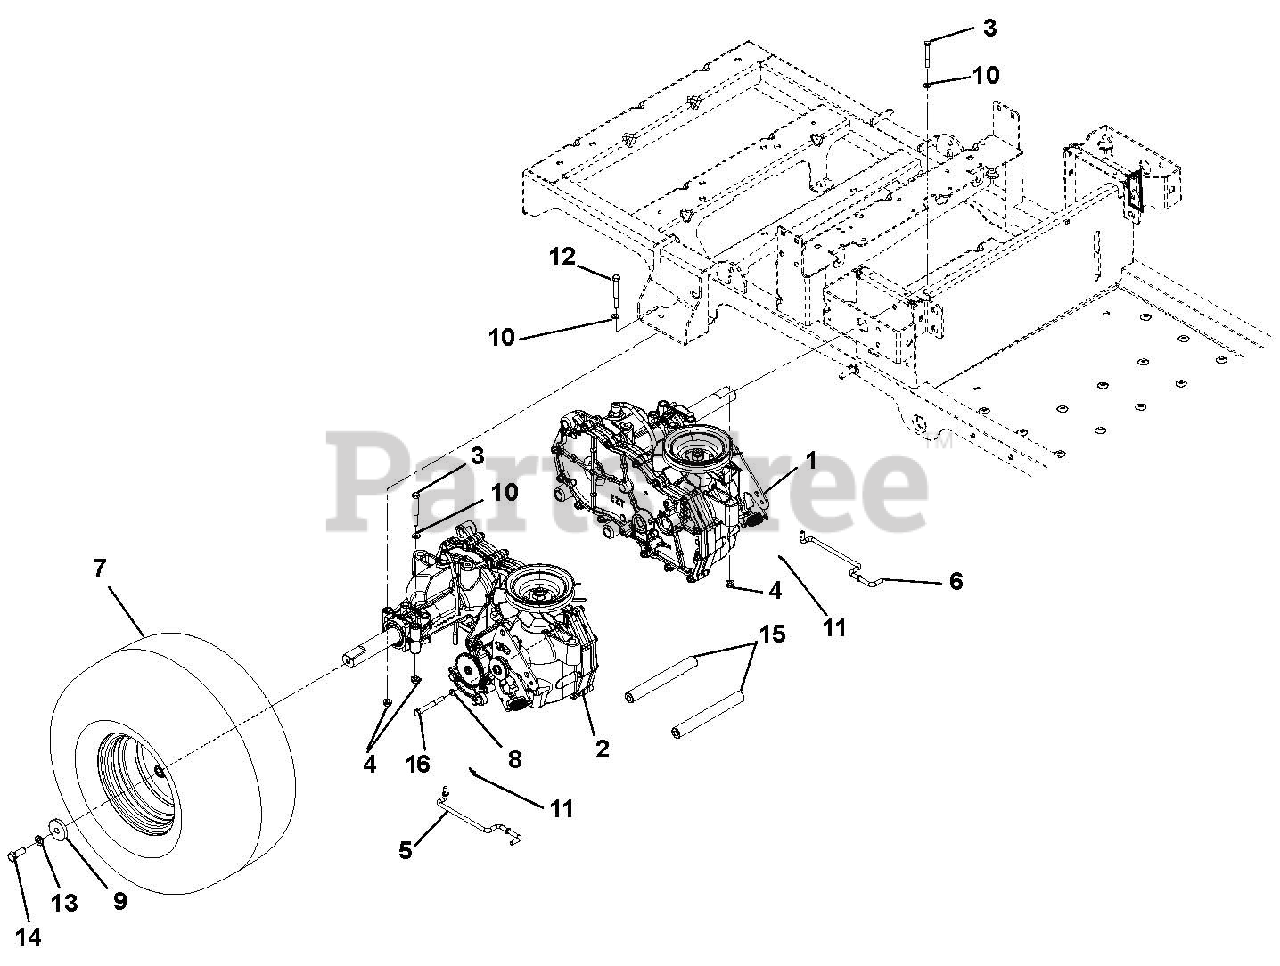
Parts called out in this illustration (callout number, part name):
1	Transaxle, Left Hand EZT D-Shaft
1	Transaxle, Left Hand EZT D-Shaft Long
2	Transaxle, Right Hand EZT D-Shaft
2	Transaxle, Right Hand EZT D-Shaft Long
3	Bolt, Hex .31-18 x 2.25
4	Nut 5/16-18 Flange Nyloc
5	Dump Valve, Right Hand
6	Dump Valve, Left Hand
7	Tire Assembly 18 x 6.5-8 2 Ply DSHAFT
7	Tire/Wheel Assembly, 18 x 8.5-8 Center
7	Tire/Wheel Assembly, 18 x 9.50-8 Offset
8	Washer, Flat Steel .406 x 1.00 x .188
9	Washer, Flat Steel .406 x 1.50 x .245
10	Washer, Flat Steel .38 x .875 x .083
11	Pin, Hair, Internal .06 x .18 x .77
12	Bolt, Hex .31-18 x 2.75
13	Washer, Locking .38 x .094 Regular
14	Bolt, Hex .38-16 x 1.00 YWZC EP30
15	Shaft, Transaxle Brace
16	BOLT, HEX .38-16 X 2.50
